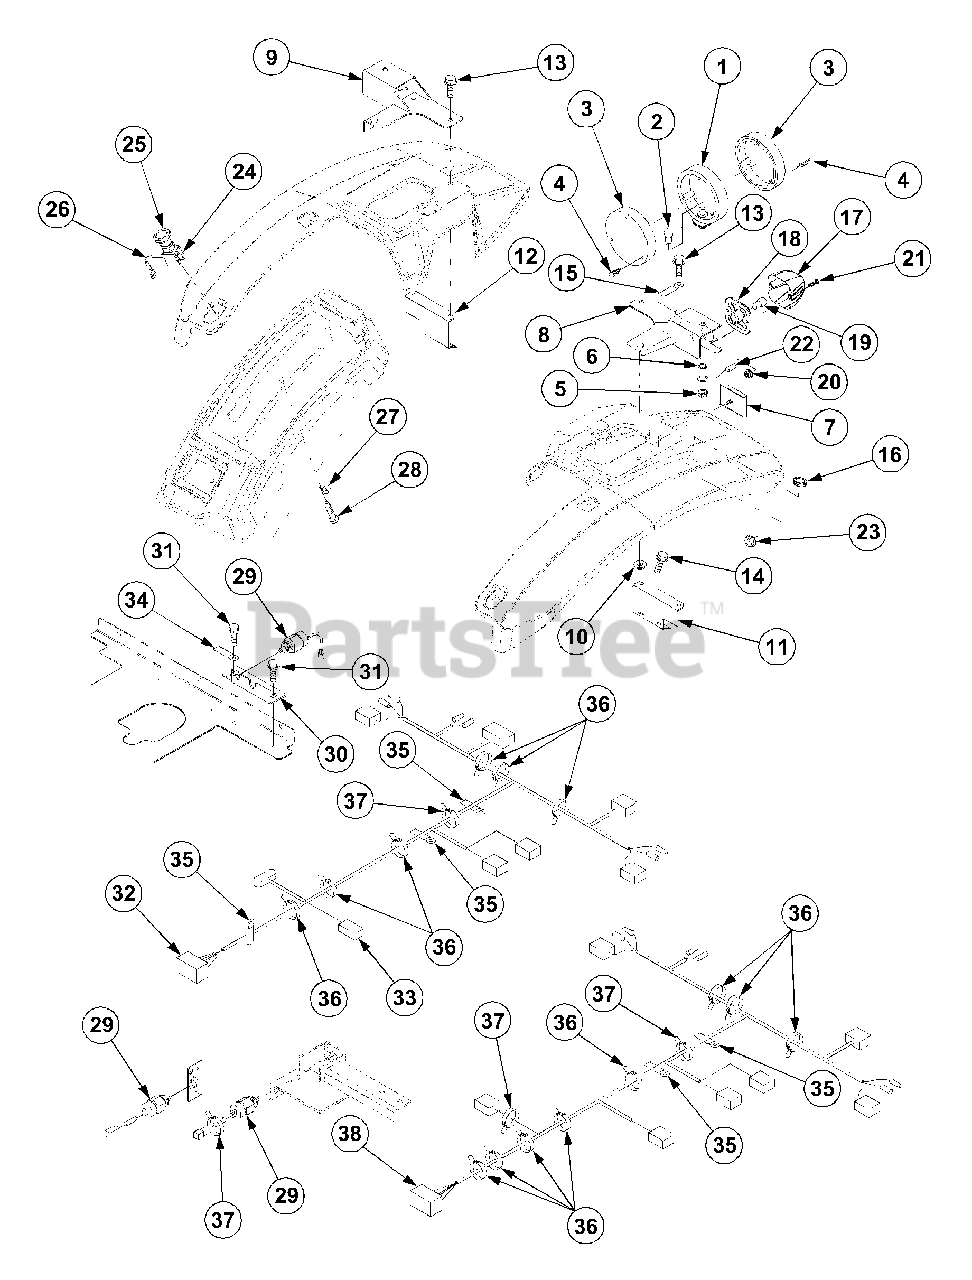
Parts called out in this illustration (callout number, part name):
2	Bulb
4	Screw,Tapping
13	Bolt,w/Washer
14	Bolt,w/Washer
17	Lens
28	Screw,Tapping
29	Switch,Safety
31	Bolt,w/Washer
32	Harness B
